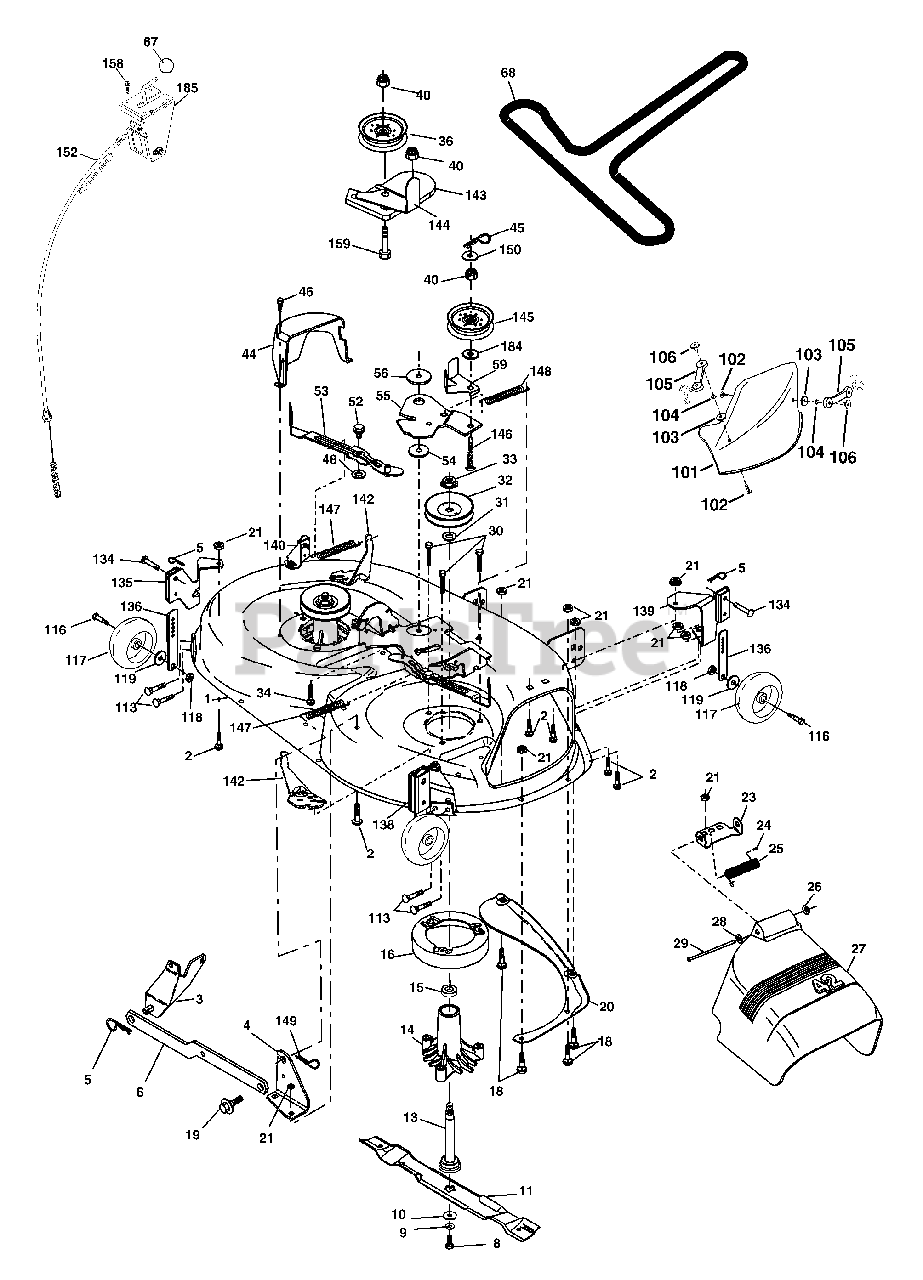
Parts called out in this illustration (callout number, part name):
1	Mower Deck Assembly, 42"
2	Bolt
3	Bracket Asm Fr. Sway Bar 3/42
4	Bracket Asm Deck 42" Sway Bar
5	Retainer Spring
6	Bar Sway Deck
8	Bolt 3/8-24 x 1.25 Gr. 8 patched
9	Washer, Lock
10	Washer, Hardened
11	Blade, Mulching 42" Std
11	Blade Mulching 42" Premium
11	Blade Mower 42" Hi-Lift
13	Shaft Assembly, Mandrel, Vented
14	Housing, Mandrel, Vented
15	Bearing, Ball, Mandrel
16	Stripper, Mandrel Deck
18	Bolt, Carriage 5/16-18 x 5/8
19	Bolt, Shoulder
20	Baffle, Vortex
21	Nut
23	Bracket, Deflector Mower 42"
24	Cap, Sleeve 80 x 112 Blk Mower
25	Spring, Torsion, Deflector 2 52
26	Nut, Push Phos & Oil
27	Shield, Deflector 42" Blk
28	Washer 11/32 x 5/8 x 16 Ga.
29	Rod, Hinge 42" 6 75 W/G
30	Screw Thdrol
31	Washer, Spacer Mower Vented
32	Pulley, Mandrel
33	Nut, Toplock
34	Bolt Carr SH 3/8-16 x 1-1/2 Gr.5
36	Pulley, Idler, Flat
40	Nut Lock 3/8-16
44	Guard, Mandrel, LH
45	Retainer
46	Screw, Thdrol 1/4-20 x 5/8 T
48	Washer, Hardened
52	Bolt, Shoulder 5/16-18 unc
53	Arm Assembly, Pad, Brake
54	Washer, Hardened
55	Arm, Idler
56	Spacer, Retainer
59	Guard TUV Idler
67	Knob Round
68	V-Belt, 42" Mower
101	Mulcher Cover
102	Screw, Pan Hd Phillip 10-24 x 5/8
103	Washer, Flat
104	Washer, Lock
105	Latch Assembly
106	Nut, Weld
113	Screw 5/16-18 x 3/4
116	Bolt, Shoulder
117	Wheel, Gauge
118	Nut Centerlock 3/8-16
119	Washer 3/8 x 7/8 x 14 Ga.
134	Pin Head Rivet
135	Bracket Asm. Whl Ga. R LH
136	Bar Adjusting Gauge Wheel
138	Bracket Asm Whl Ga. R RH
139	Bracket Asm. Whl Ga. F RH
140	Bracket Asm Whl Ga. F LH
142	Arm Spring Brake Mower
143	Bracket Arm Idler 42"
144	Keeper Belt 42" Clutch Cable
145	Pulley Idler Flat
146	Bolt Carriage Idler
147	Spring Extension
148	Spring Return Idler
149	Retainer Spring Yellow
150	Washer 9/32 x 3/4 x 10 Ga.
152	Clutch Cable 42"
158	Screw Hex Thd Cut 1/4-20 x 1/2
159	Bolt Rdhd Sqn 3/8-16 unc x 1-3/4
184	Washer 13/32 x 7/8 x 10 Ga.
185	Head Asm Cable Clutch
